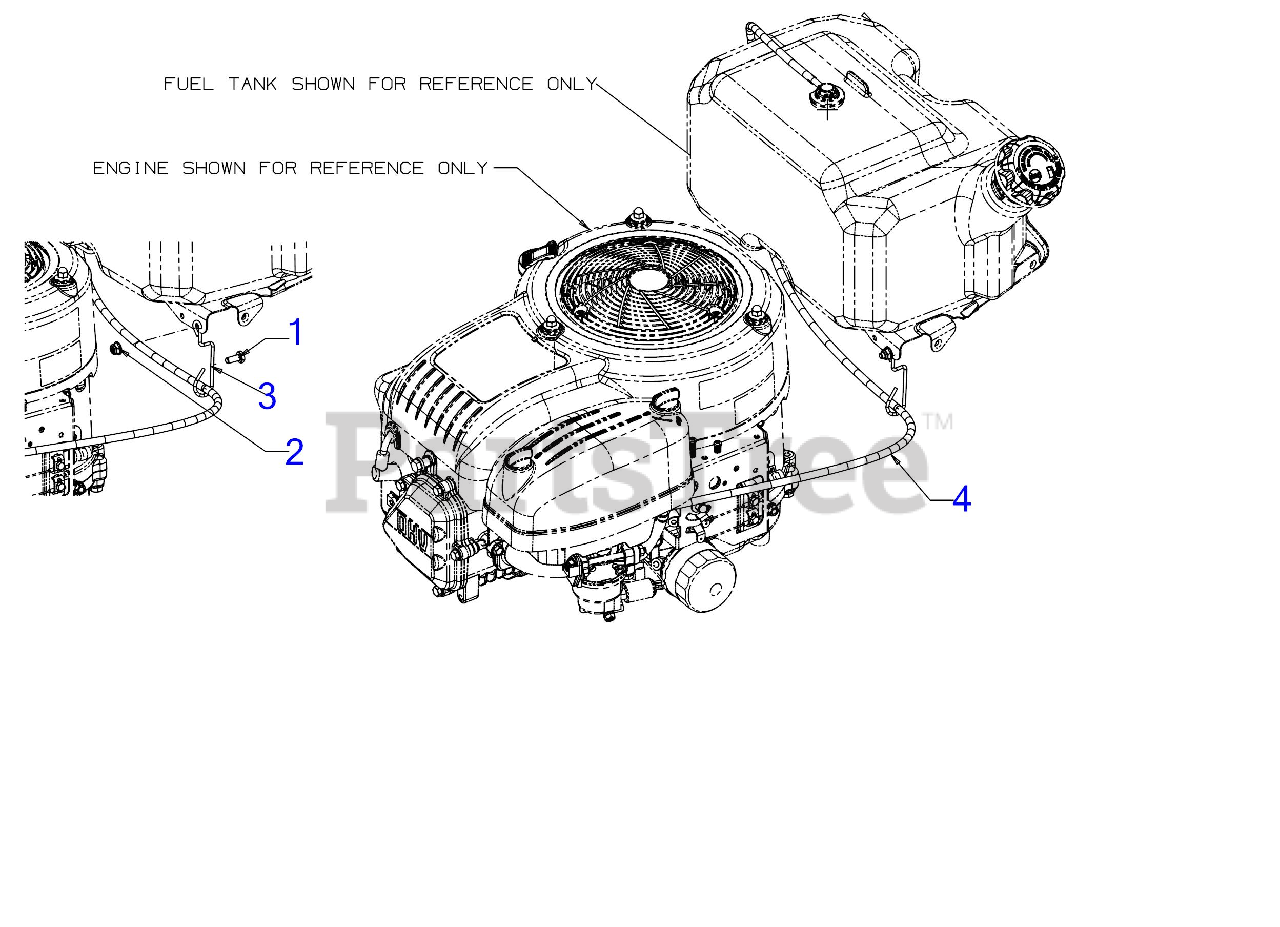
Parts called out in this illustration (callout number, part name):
1	SCREW 1/4-20 x .620 GR5
2	FLANGE LOCK NUT
3	CABLE GUIDE WIRE
4	VENT HOSE 3/16 ID
